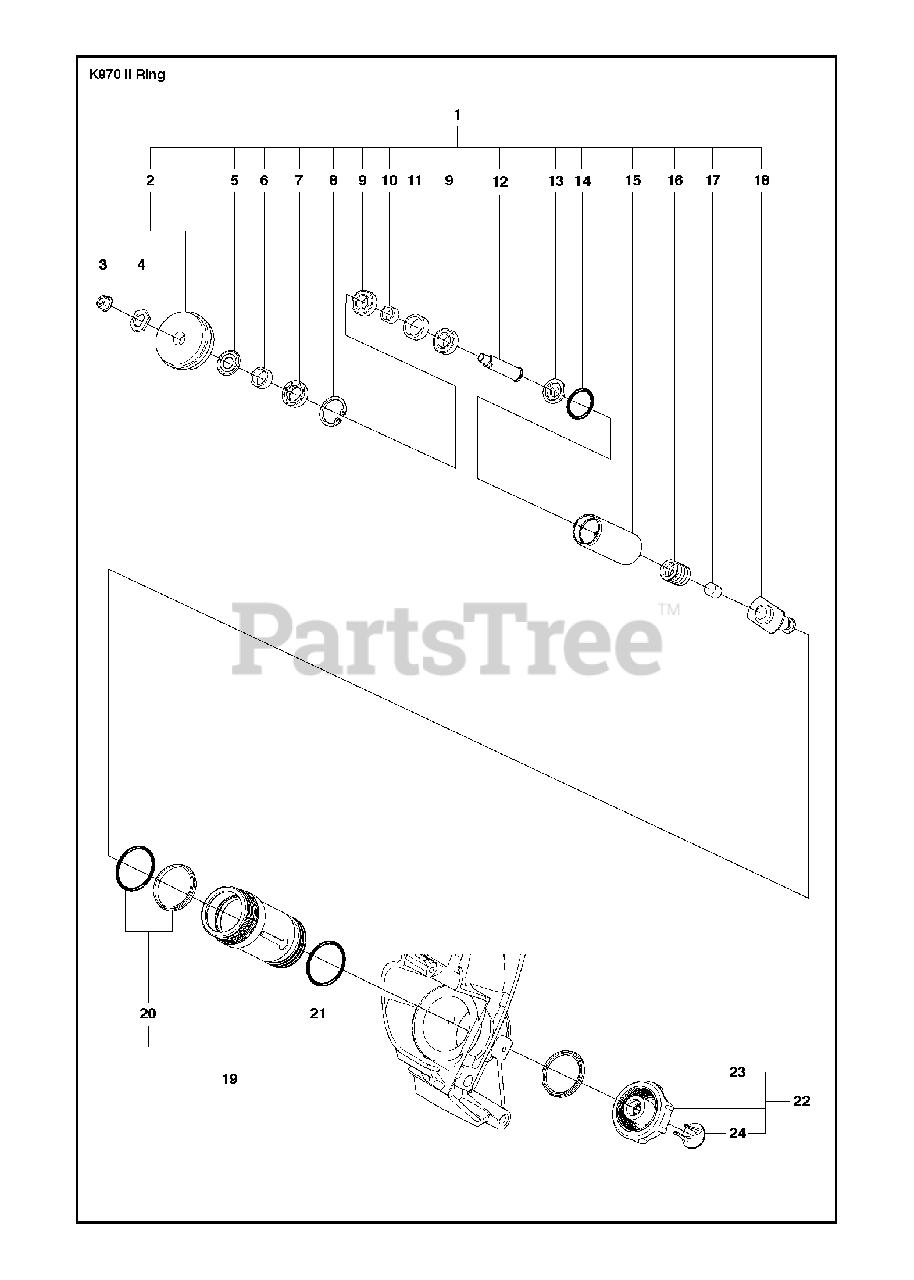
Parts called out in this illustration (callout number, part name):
1	BEARING CAGEIncl. 2, 5 - 18
2	GUIDE ROLLERIncl. 3, 4
9	BALL BEARING
19	SLEEVEIncl. 20, 21
